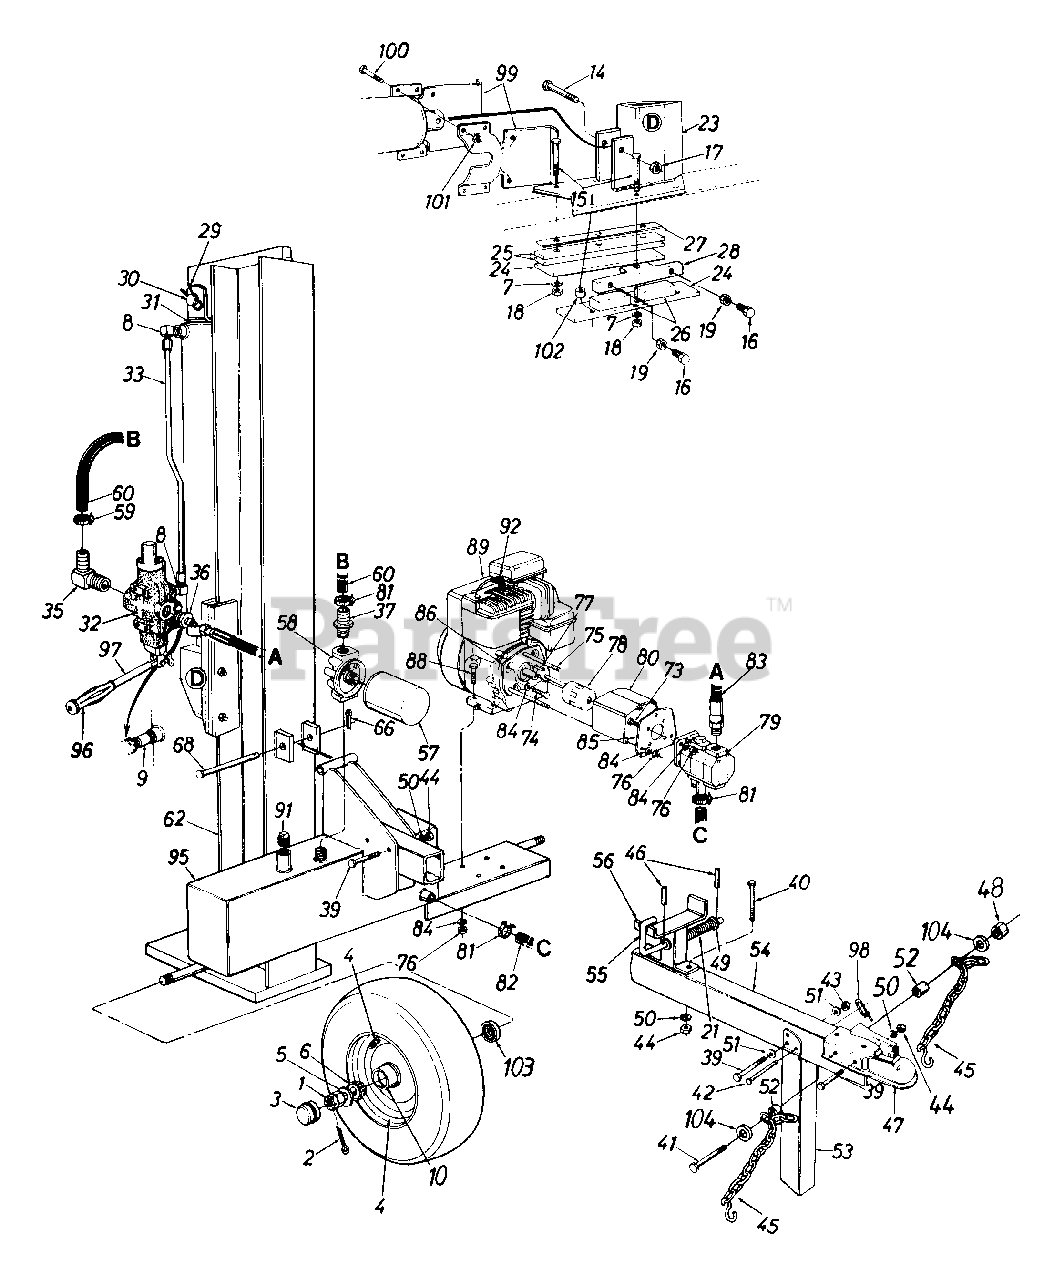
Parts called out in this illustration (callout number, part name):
1	Slotted Nut 3/4-16 Thd.
2	Cotter pin 5/32" Dia.
5	Fl-Wash. .76" I.D. x 1.5" O.D.
6	Bearing Cone
7	L-Wash. 1/2" I.D.
8	90° Solid Male Adaptor
9	Pipe Nipple 1/2 NPT
10	Bearing Cup
14	Hex Bolt 1/2-20 x 3" Lg. (Grade 8)
15	Hex Bolt 1/2-20 x 2.75" Lg. (Grade 8)
16	Hex Bolt 3/8-24 x 1.5" Lg.
17	Hex L-Nut 1/2-20 Thd.
18	Hex Nut 1/2-20 Thd.
19	Hex Jam Nut 3/8-24 Thd. (Grade 5)
21	Comp. Spring 4" Lg.
26	Adjustable Gib
29	External Cotter Pin
30	Cylinder Mounting Pin
31	Hydraulic Cylinder
33	Metal Pressure Tube
35	Return Elbow
37	3/4" Hose Barb.
39	Hex Bolt 3/8-16 x 3" Lg. (Grade 8)
40	Hex Bolt 3/8-16 x 4" Lg.
41	Hex Bolt 3/8-16 x 4" Lg. (Grade 5)
42	Clevis Pin 5/16 x 2.5" Lg.
43	Hex L-Nut 3/8-16 Thd.
44	Hex Nut 3/8-16 Thd.
45	Chain - Tow Hitch
47	Hitch Coupler
48	Hex Ctr. L-Nut 3/8-16 Thd.
49	Fl-Wash. .635" I.D. x .93" O.D.
50	L-Wash. 3/8" I.D.
51	Fl-Wash. .406" I.D. x .75" O.D.
52	Spacer .27" Lg
57	Filter Element
58	Filter Head
59	Adj. Hose Clamp
60	Return Hose 3/4" I.D. x 44" Lg.
62	Vertical Beam Ass'y.
66	Cotter Pin 1/8" Dia.
68	Hinge Pin 1/2 x 4.8" Lg.
73	Hex Bolt 5/16-24 x 1" Lg.
74	Hex Bolt 5/16-24 x .62" Lg.
75	Hex Bolt 5/16-24 x 5" Lg.
76	Hex Nut 5/16-24 Thd.
77	Sq.-Key 3/16" x .75"
78	Flexible Coupling
79	Two Volume Pump
80	Coupling Shield
81	Hose Clamp 5/8"
82	Suction Hose 3/4" I.D. x 22" Lg.
83	High Pressure Hydraulic Hose 62"
84	L-Wash. 5/16" I.D.
88	Hex Bolt 5/16-24 x 1.75" Lg.
89	Engine
91	L-Vent Pipe Plug
92	Spark Plug Boot
96	Grip
97	Control Handle
101	Hex L-Nut 3/8-16 Thd.
102	Spacer 1/2" I.D. x .68" Lg.
103	Bearing Seal Only
104	Fl-Wash. 3/8" I.D. x .87" O.D.
